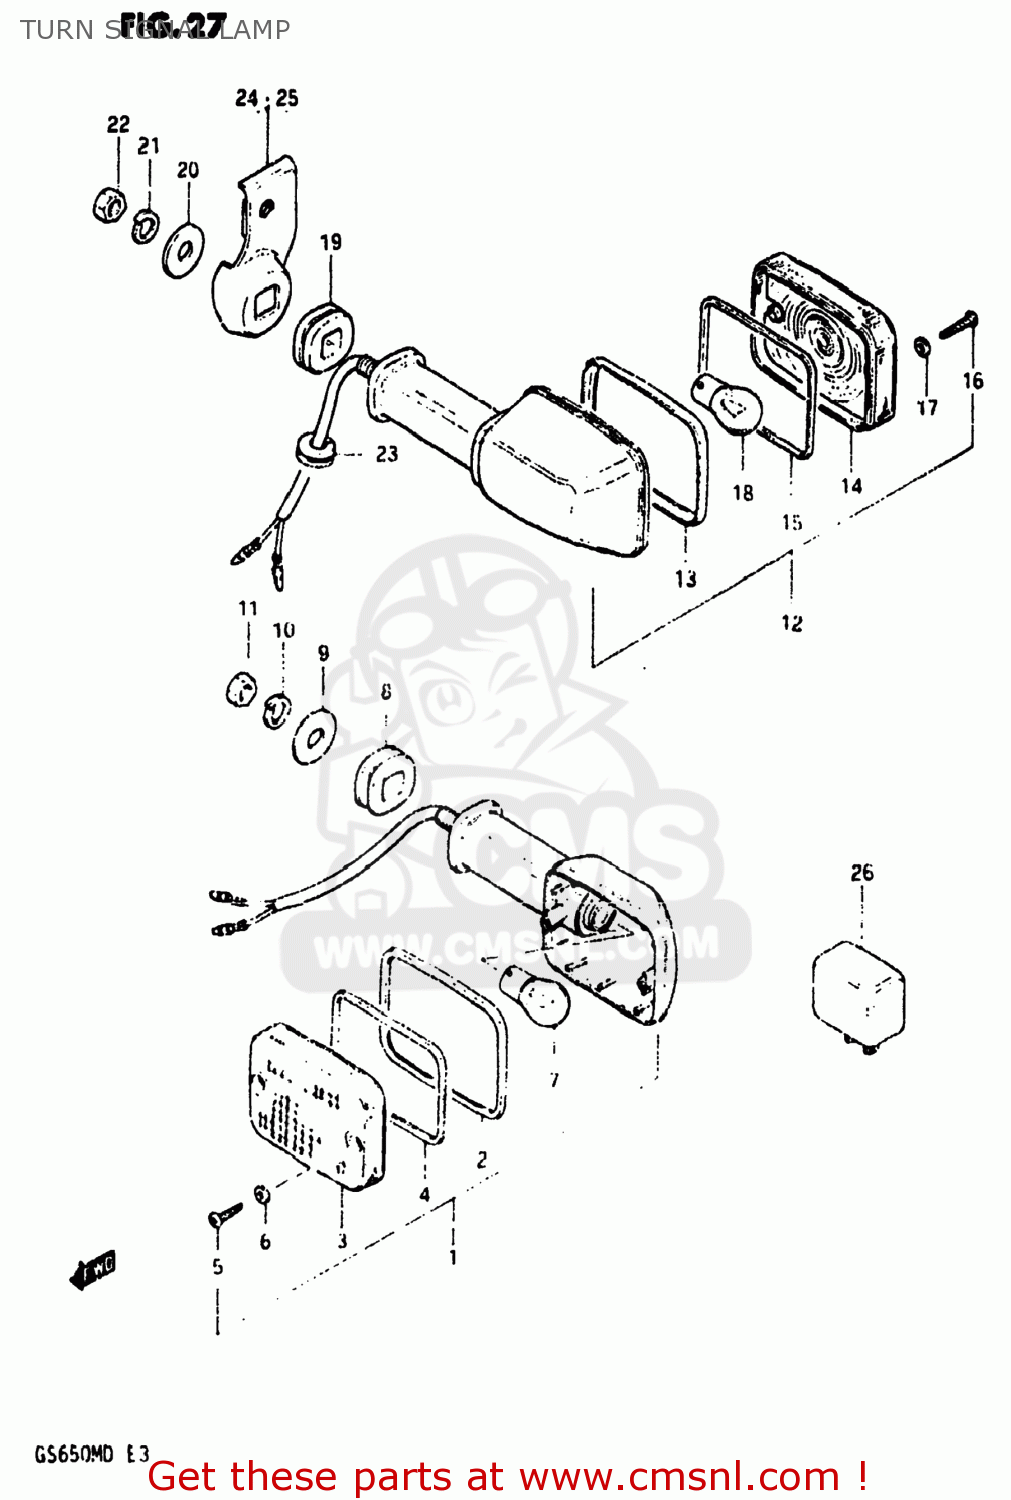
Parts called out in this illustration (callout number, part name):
1	LAMP ASSEMBLY,FRONT TURN SIGNAL
2	RIM
3	LENS
4	GASKET (NAS)
5	SCREW
6	GASKET (NAS)
7	BULB(12V23W,STANLEY,A4577A)
8	CUSHION
9	WASHER (10.5X30X2.3)
10	LOCK WASHER
11	NUT
12	LAMP ASSEMBLY,FRONT TURN SIGNAL
13	RIM
14	LENS
15	GASKET (NAS)
16	SCREW
17	GASKET (NAS)
18	BULB(12V23W,STANLEY,A4577A)
19	CUSHION
20	WASHER (10.5X30X2.3)
21	LOCK WASHER
22	NUT
23	GROMMET
24	BRACKET,REAR TURN SIGNAL
25	BRACKET,REAR TURN SIGNAL
26	RELAY,TURN SIGNAL
